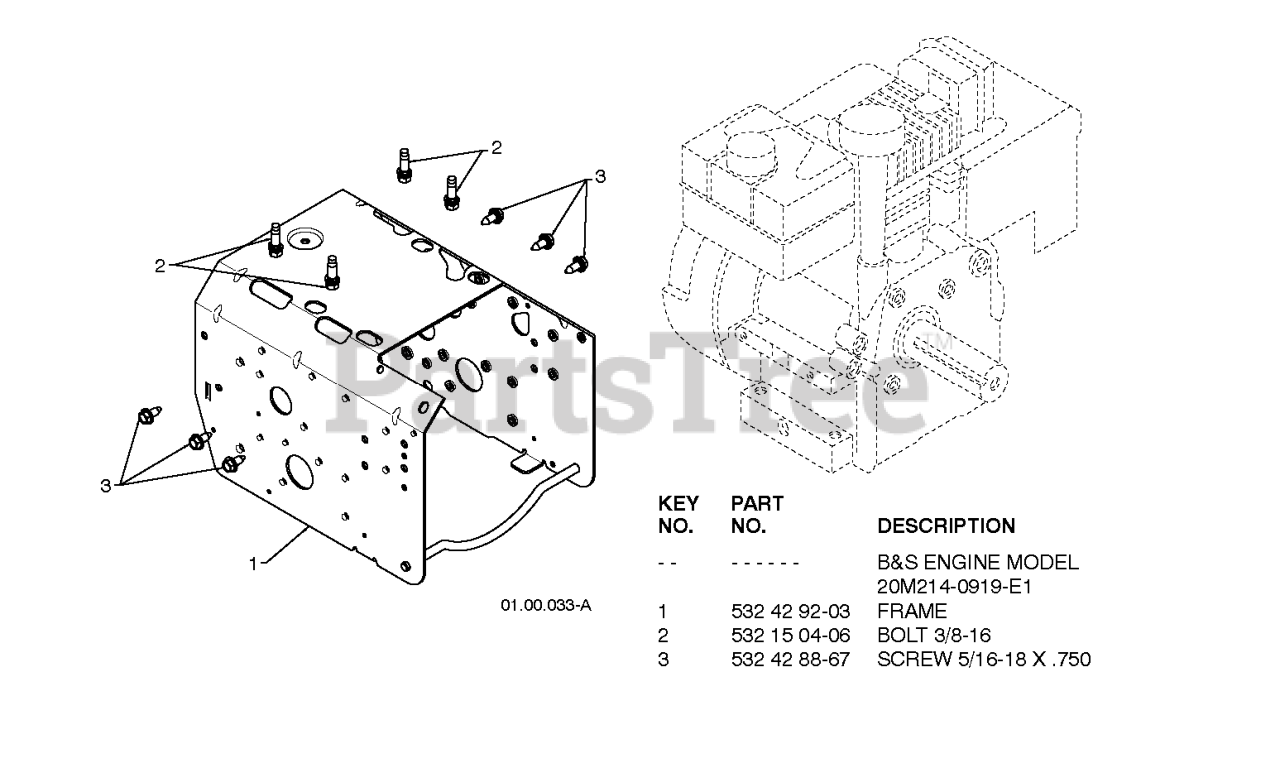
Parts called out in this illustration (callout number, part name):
1	FRAME.WELD.PNT.GEAR.ORANGE
2	BOLT 3/8-16X1-1/8
3	BOLT.HEX.HD.WASHER.5/16-18X.75
